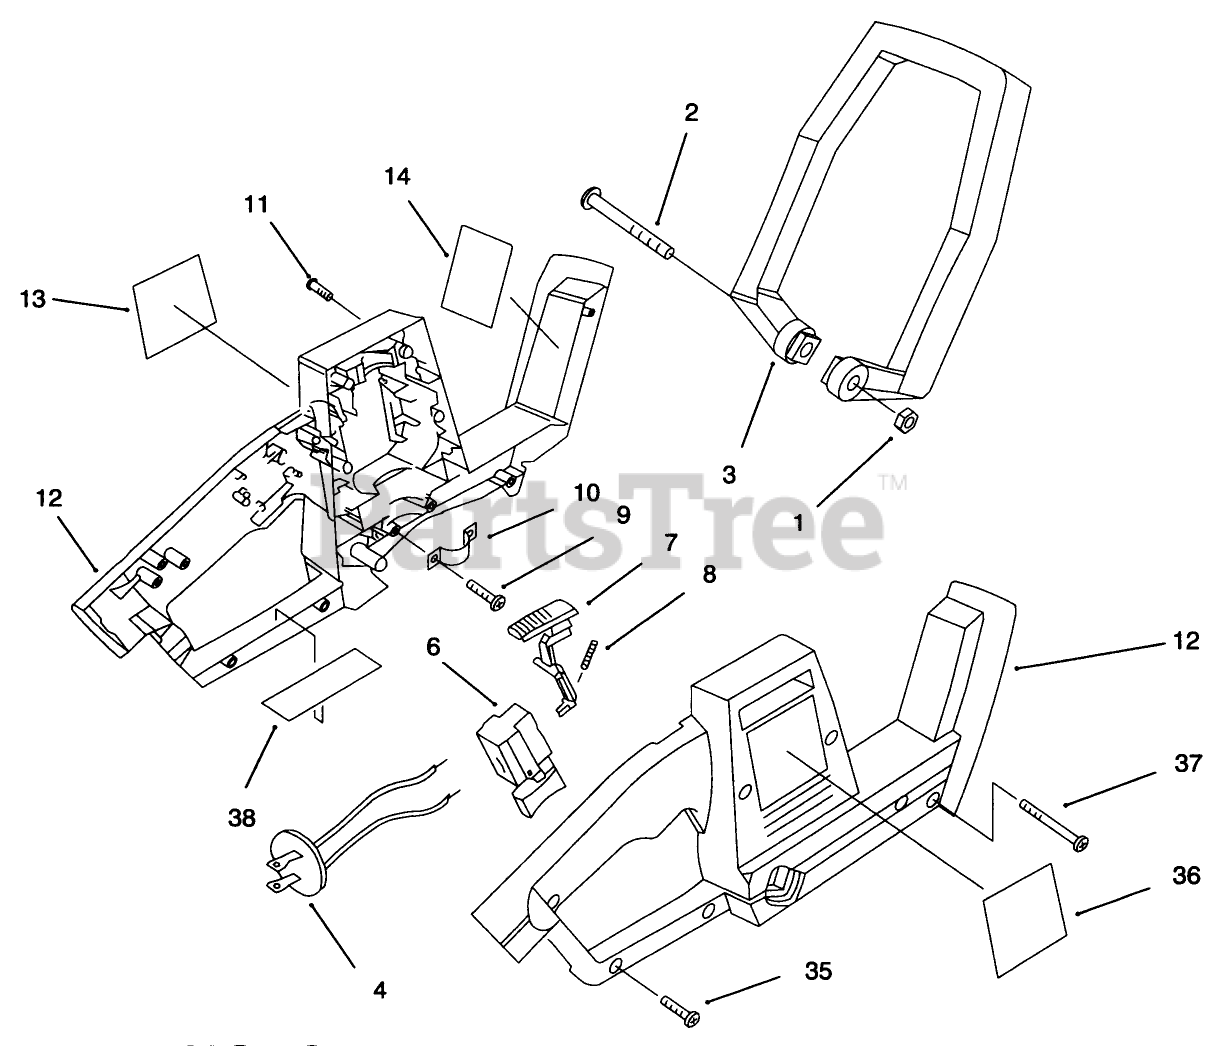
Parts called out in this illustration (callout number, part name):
1	NUT - HEX
2	SCREW
3	HANDLE - FRONT
4	ASSEMBLY - DISC
6	SWITCH
7	BUTTON - LOCK-OFF
8	SPRING
9	SCREW
10	STRAP - BEARING
11	SCREW
12	ASSEMBLY - HOUSING
13	PLATE - LOGO
14	LABEL - DANGER
35	SCREW
36	LABEL - WARNING
37	SCREW
38	PLATE - DATA
